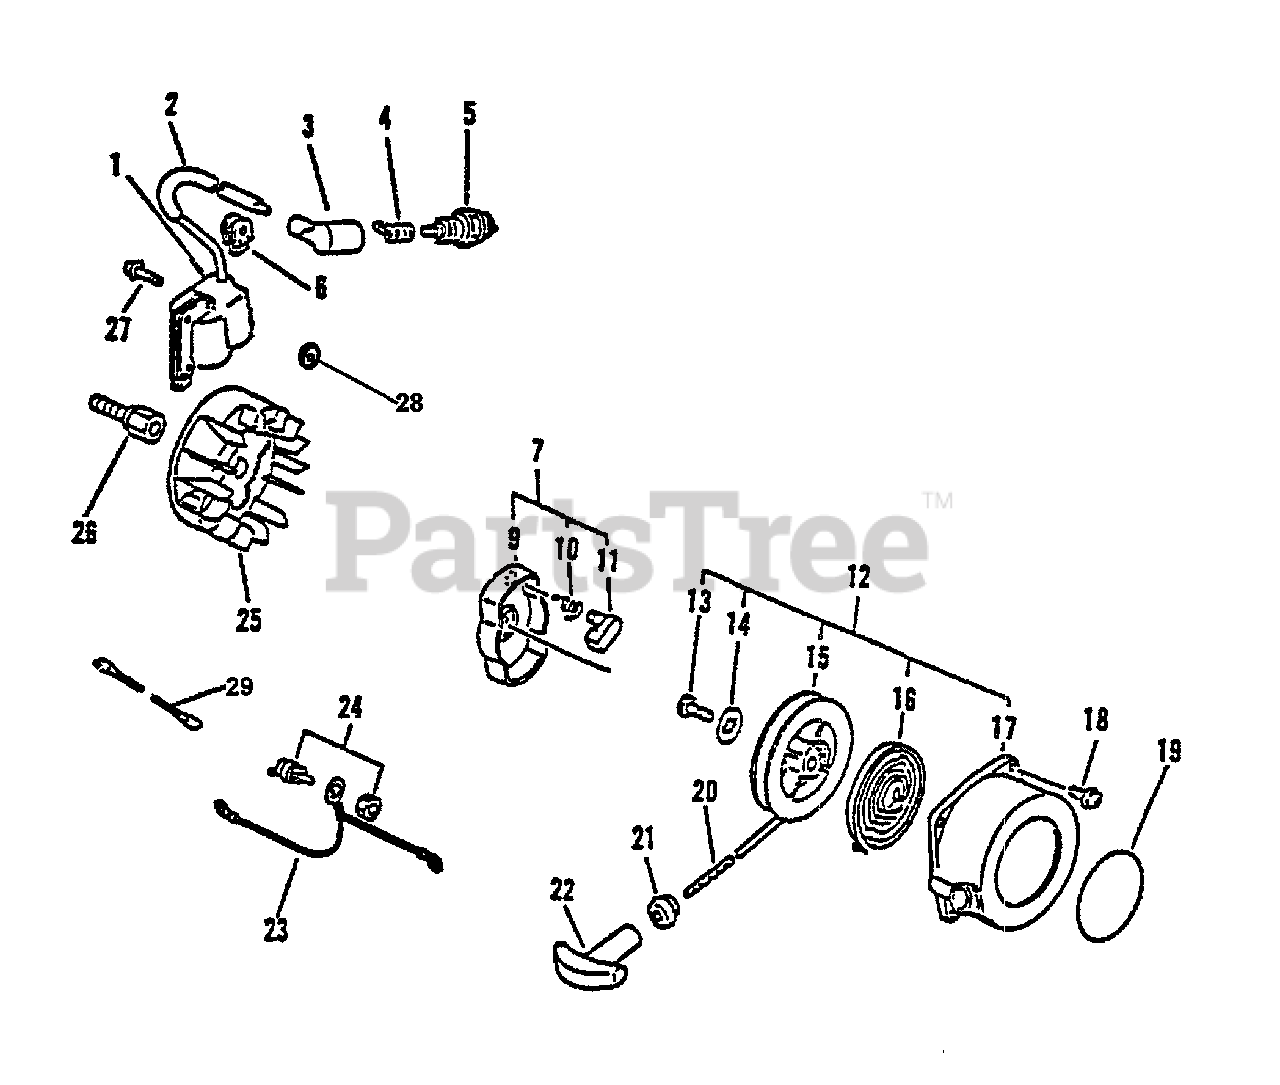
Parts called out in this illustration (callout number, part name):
1	COIL, IGNITION
3	CAP, SPARK PLUG
4	TERMINAL, SPARK PLUG CAP
5	SPARK PLUG -- BPM-7A
5	SPARK PLUG -- BPMR-7A
7	STARTER PAWL ASSY
9	CATCHER, PAWL
10	SPRING, RETURN
11	PAWL, STARTER - BLACK
12	STARTER ASSY
14	WASHER
15	REEL, ROPE
16	SPRING, REWIND
17	CASE, STARTER
18	SCREW - 4X18
19	LABEL - ECHO
20	ROPE, STARTER - 3X1000
21	GUIDE, ROPE
22	GRIP, STARTER
23	LEAD - GROUND
24	IGNITION SWITCH ASSY
25	FLYWHEEL
26	HUB, FAN
27	SCREW - 4X22
28	SPACER
29	LEAD - IGNITION
